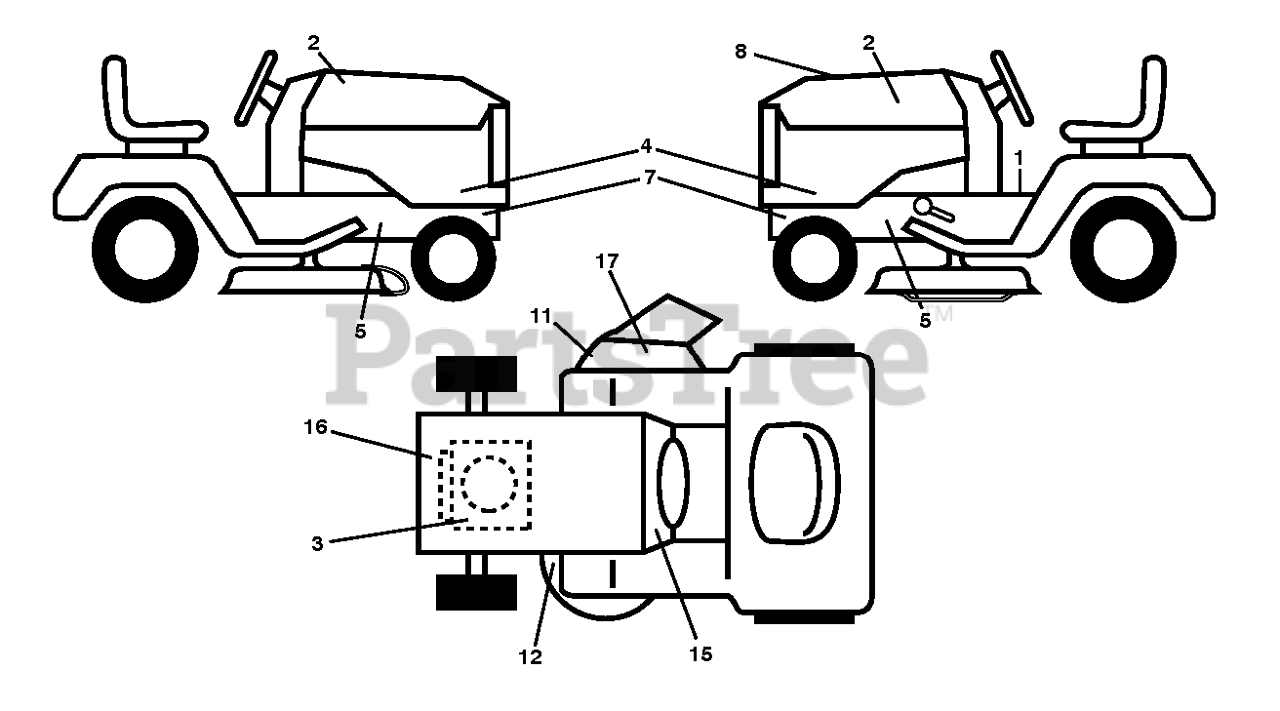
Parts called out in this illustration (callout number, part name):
1	STEERING WHEEL
2	FRONT AXLE ASSY
3	ZERK M
4	SPINDLE ASSY LH
5	SPINDLE ASSY RH
6	THRUST WASHER
9	CAP.SPINDLE.BLACK
10	Bolt, Hex 5/8 -11 x 2 - 3/4 Gr. 5
11	TUBE, PIVOT AXLE
12	NUT-LOC,FLANGE LT
14	WASHER, LOCK 3/8
15	GRIPCO NUT
16	SHAFT ASM, STEERING
17	ROD ASSY/TIE BALL
18	DRAGLINK-BALL JOINT SOLID
19	SUPPORT ARM, STEERING VGT
21	ADAPTER LT
22	BUSHING, STRG. BLK
23	SCREW.TT.#10-32X.5.3/8.FLANGE
24	WASHER T
26	INSERT,STR WHEEL
27	BRNG T
28	SCREW
29	BEARING-FLANGE GT
30	Ring, Klip Truarc #5304-75
31	BUSHING.NYLINER.
33	WASHER.LOCK.HVY.HLCL.SPR.5/16
34	BOLT
35	GEAR.ASM.SECTOR.
36	TIE ROD
38	JOINT
